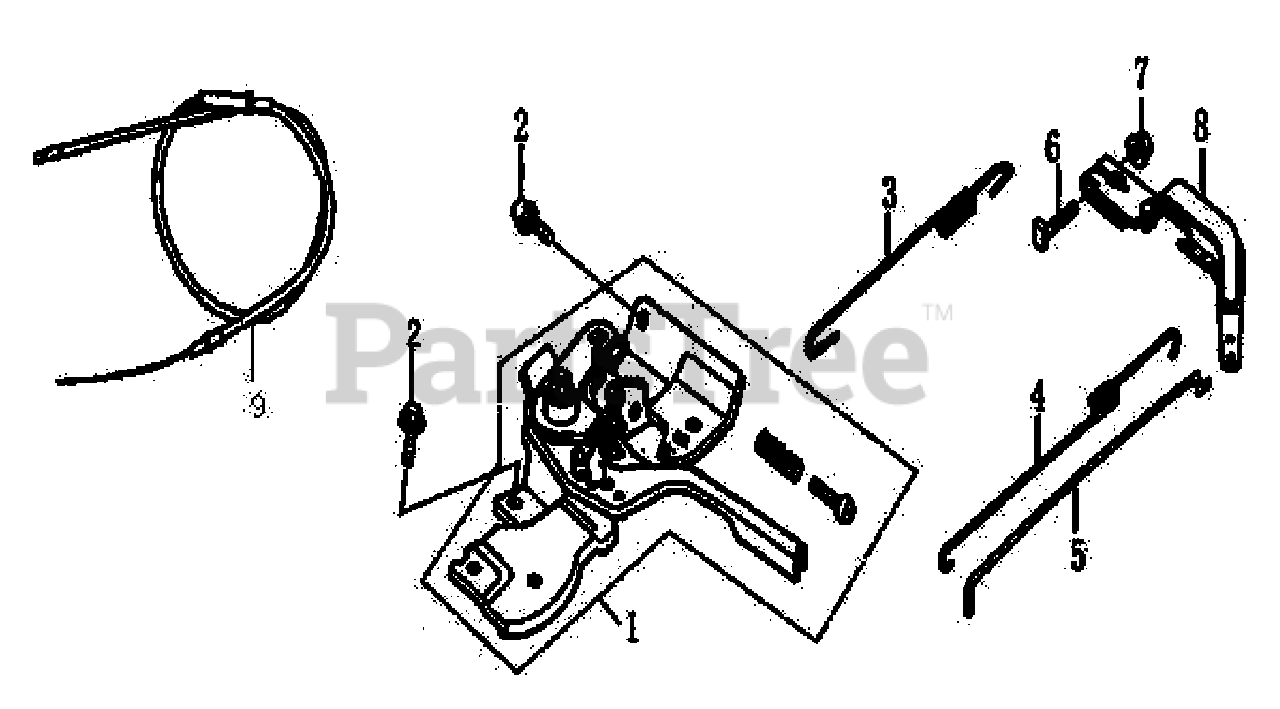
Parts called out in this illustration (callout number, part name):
1	CONTROL ASSEMBLY
2	BOLT, FLANGE
3	SPRING, GOVERNOR
4	SPRING, THROTTLE RETURN
5	ROD, GOVERNOR
6	BOLT, GOVERNOR ARM M6X21
7	NUT, FLANGE
8	ARM, GOVERNOR
9	CABLE, CHOKE
